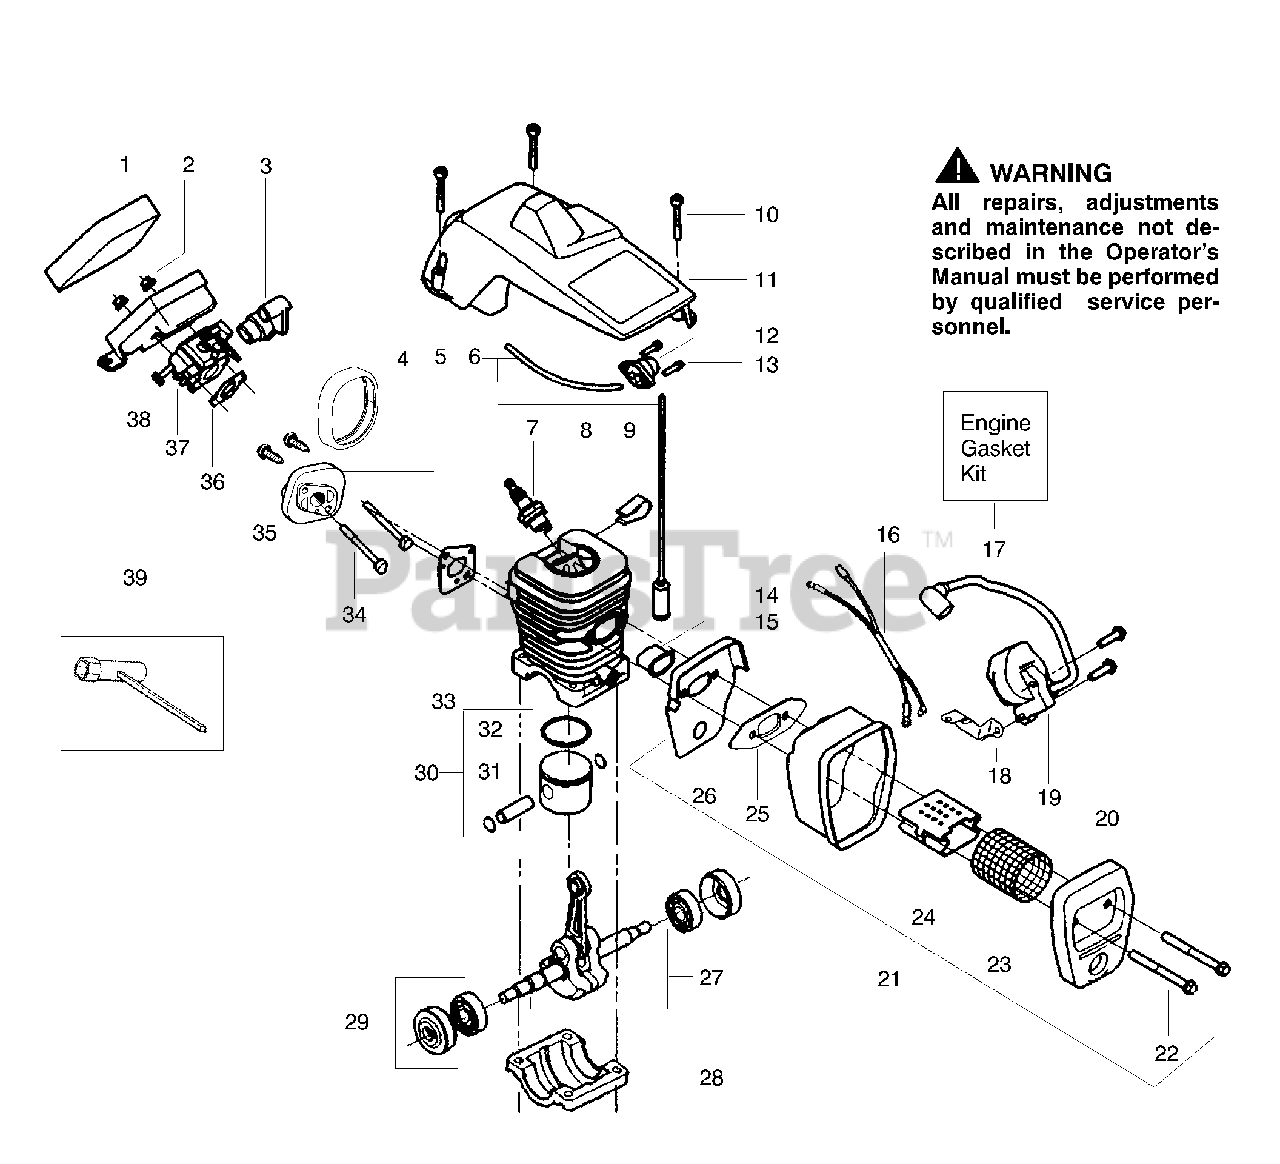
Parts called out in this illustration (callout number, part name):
1	Foam Air Filter
3	Grommet Carb Adjust
4	Seal Carb Adapter
5	Adapter Carb.
6	Kit Fuel Line (Small)
7	Spark Plug (RCJ 7Y)
8	Kit Cylinder
9	Clip High Tension Lead
11	Shield Cylinder
12	Assy Air Purge
14	Assy Fuel Pickup
15	Insulator Heat
16	Assy. Wire Harness
17	Kit Engine Gasket
18	Strap Ground
19	Module Ignition
21	Assy Muffler
23	Screen Spark
24	Diffuser Muffler
25	Gasket Muffler (kit)
26	Backplate Muffler
27	Assy. Crankshaft
28	Cap Crankcase
29	Assy. Seal & Bearing
30	Kit Piston
31	Retainer Piston Pin
32	Ring Piston
33	Gasket Adapter(kit)
36	Gasket Carb.(kit)
37	Kit Carburetor (WT624)
38	Housing Air Filter
39	Wrench Bar
